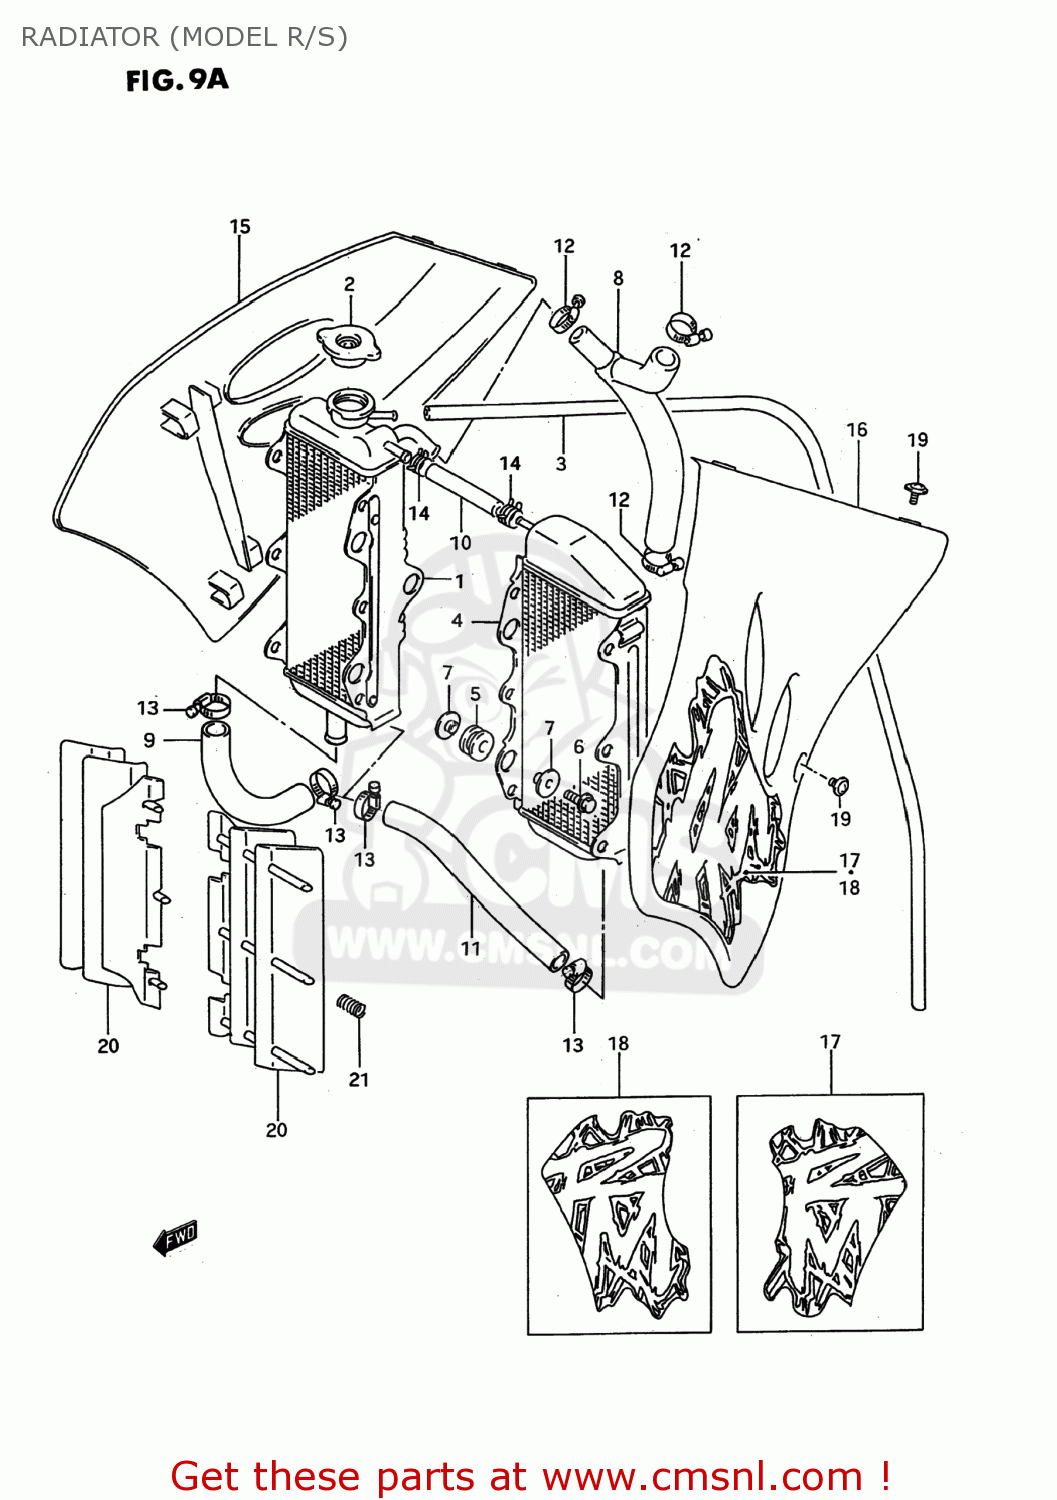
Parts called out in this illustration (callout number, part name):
1	RADIATOR ASSEMBLY,WATER
2	CAP,RADIATOR
3	HOSE(5X8X2000)
4	RADIATOR,WATER,L
5	CUSHION,RADIATOR LWR
6	SCREW
7	WASHER,RDTR SPRT
8	HOSE,RADIATOR INLET
9	HOSE,RADIATOR OUTLET
10	HOSE,WATER
11	HOSE,RADIATOR JOINT
12	CLAMP
13	CLAMP
14	CLIP
15	COVER,RADIATOR
16	COVER,RADIATOR
17	EMBLEM,RADIATOR COVER
18	EMBLEM,RADIATOR COVER
19	SCREW(6X12)
20	LOUVER,RADIATOR
21	SPRING
